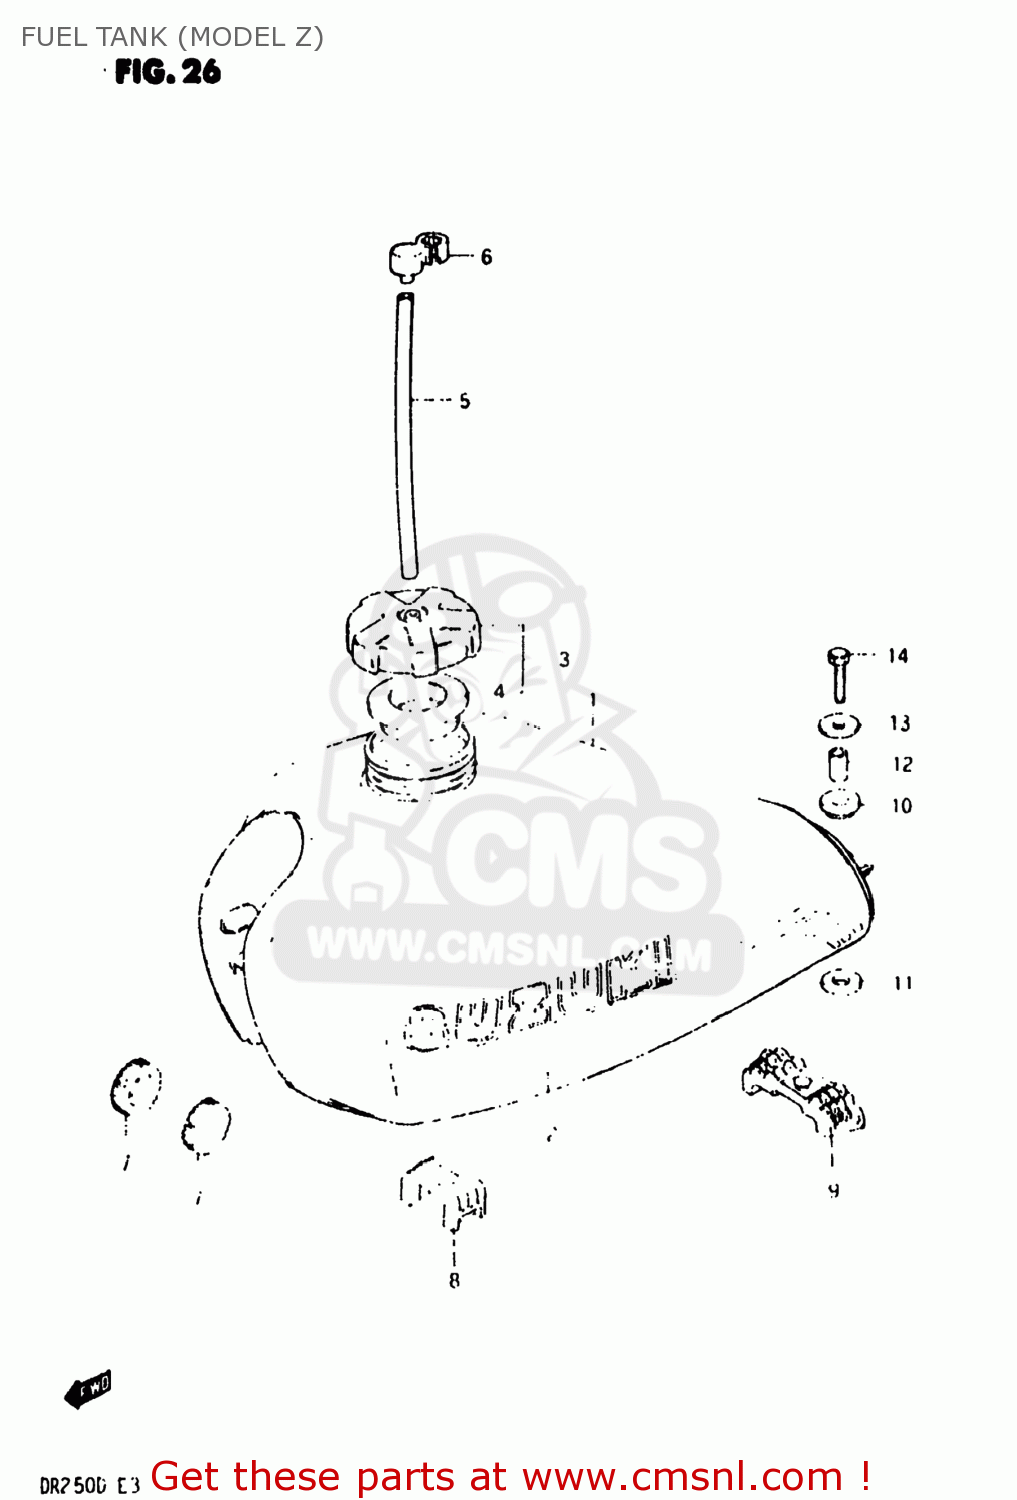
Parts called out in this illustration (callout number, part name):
1	TANK ASSEMBLY,FUEL
2	TAPE SET,FUEL TANK
3	CAP SET,FUEL TANK
4	GASKET (NAS)
5	HOSE
6	CLAMP,FUEL TANK BREATHER HOSE
7	CUSHION
8	CUSHION,TANK UPR FR
9	CUSHION,FUEL TANK,REAR
10	CUSHION
11	CUSHION
12	SPACER(8.5X12X19)
13	WASHER (8.5X29X1.6)
14	BOLT (8X30)
